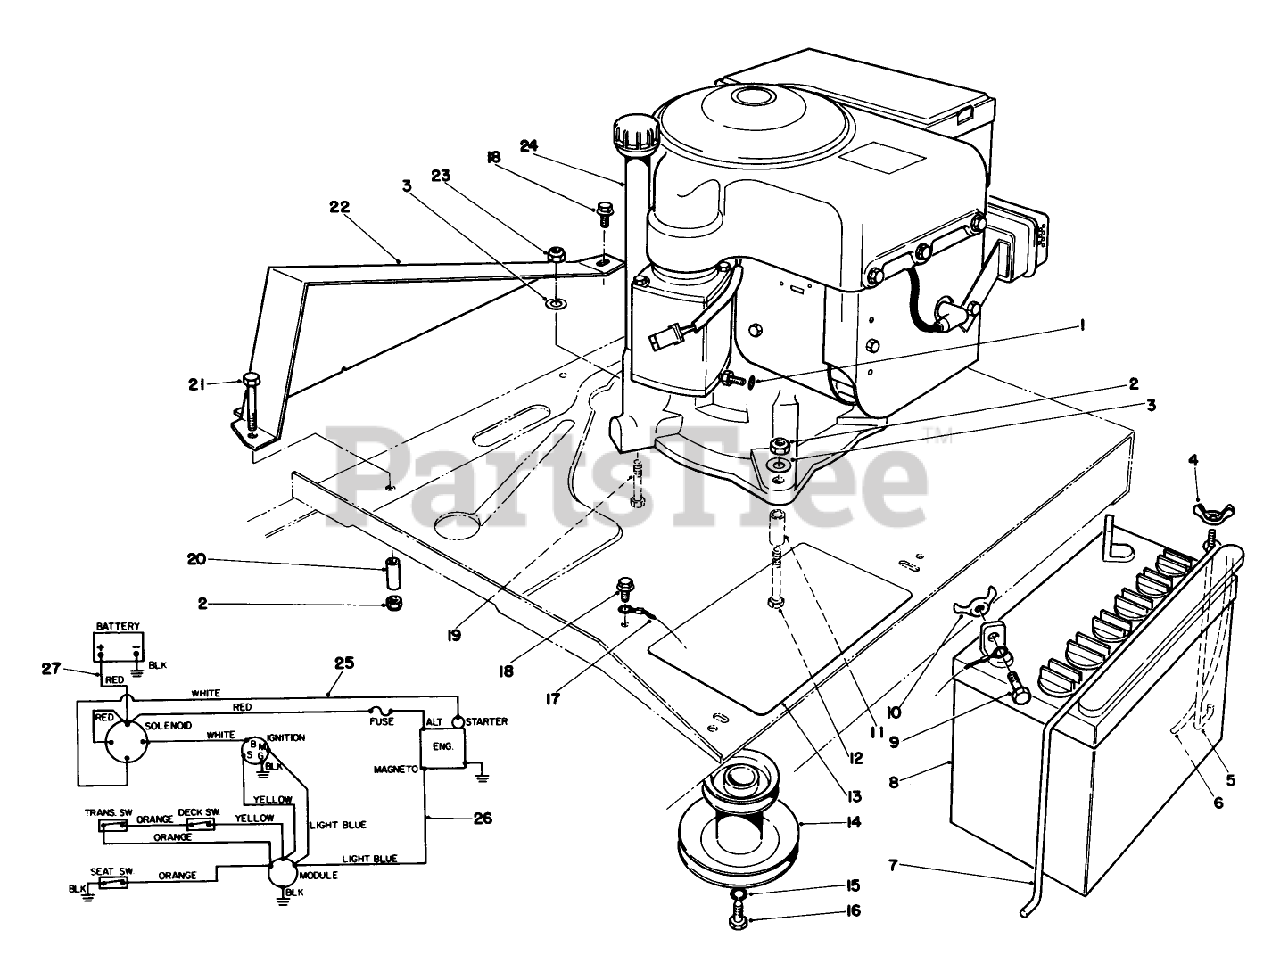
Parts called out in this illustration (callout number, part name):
1	WASHER-LOCK
2	NUT-LOCK, NI
3	WASHER-PLAIN
4	NUT-WING SPECL
6	TUBE-BATT DRAIN/80-2600
7	BATTERY HOLDOWN
9	SCREW-HH
10	NUT-WING
11	PIVOT SPACER
12	SCREW-HH
13	PAD-SKID, ANTI
15	WASHER-LOCK
16	SCREW-HH
17	ENG-GROUND WIRE ASM
18	SCREW-HWHTF
19	SCREW-HH
20	GUIDE-BELT
21	SCREW-HH
23	NUT-LOCK, CONE
24	Engine Assy.
